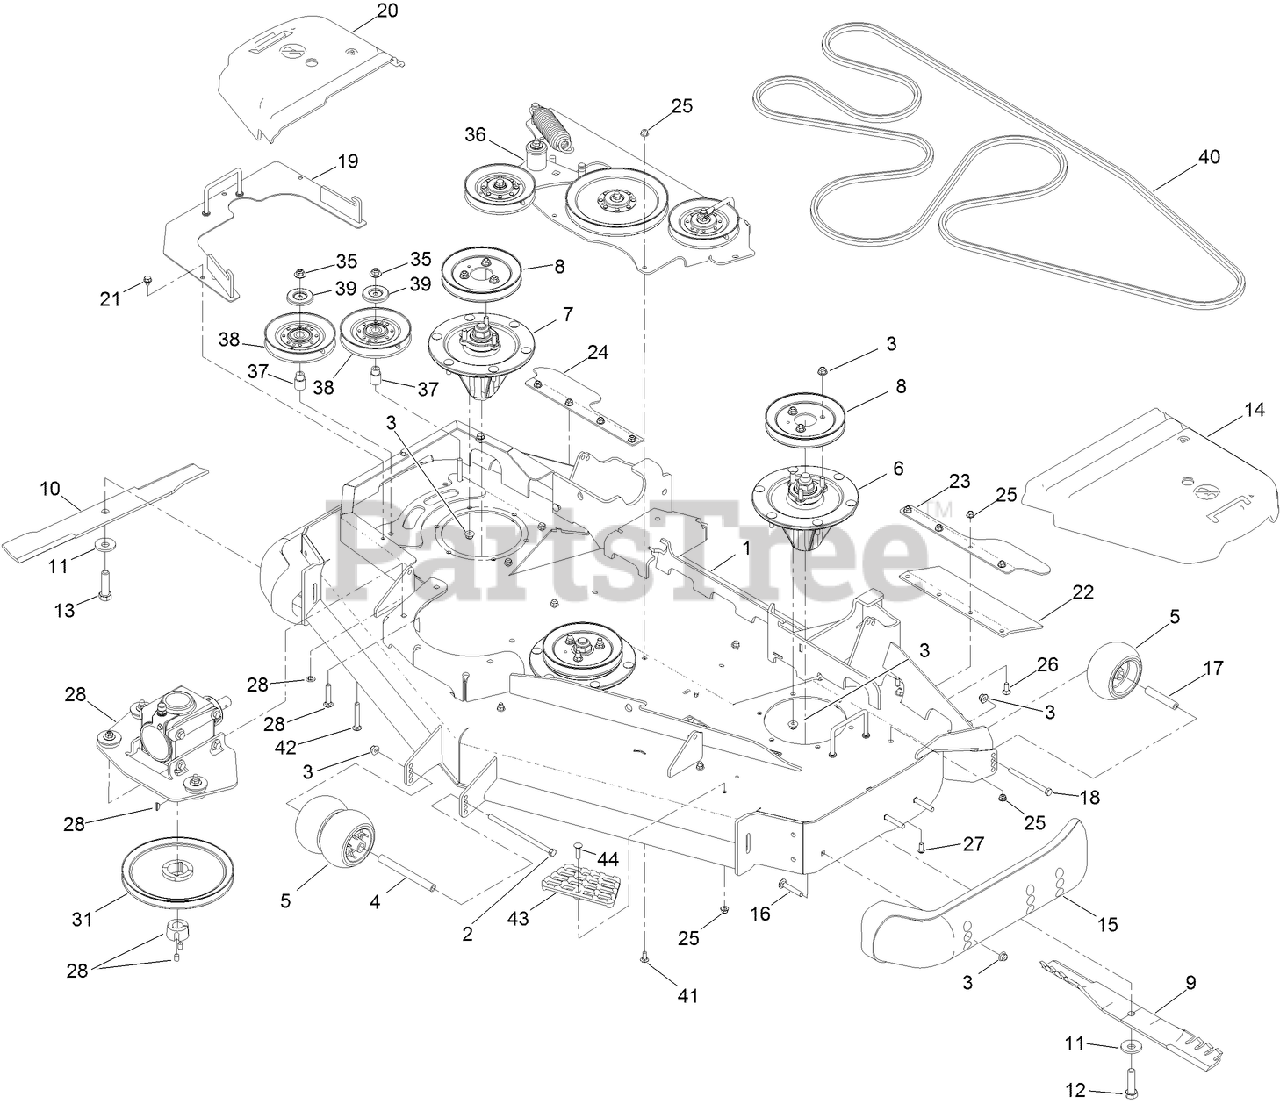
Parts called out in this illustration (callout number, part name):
1	DECK DECAL ASM
2	SCREW-HH
3	NUT-HF, NI
4	SPACER-WHEEL
5	ROLLER-SCALP, ANTI
6	SPINDLE ASM
7	LH SPINDLE ASM
8	PULLEY
9	BLADE-ATOMIC, 20.5IN
10	BLADE-ROTARY, 20.5IN LOW FLOW
11	WASHER-BLADE BOLT, HEAVY
12	SCREW-BLADE
13	SCREW-BLADE, LH
14	COVER-BELT, LH
15	SKID-BUMPER, DECK
16	SCREW-HH
17	TUBE-SPANNER
18	SCREW-HH
19	COVER-DRIVE REVERSE
20	COVER-BELT, RH
21	SCREW
22	GUARD-TIRE
23	SUPPORT-FLAP, OUTER (LH)
24	SUPPORT-FLAP, OUTER (RH)
25	NUT-HF, NI
26	SCREW-CARR
27	SCREW-HSBH
28	GEARBOX ASM
31	PULLEY
35	NUT-FLANGE, NI
36	IDLER MOUNT ASM
37	STANDOFF-IDLER
38	IDLER V
39	SHIELD-DUST
40	BELT-BB
41	SCREW-CARR
42	SCREW-CARR
43	STEP-DECK
44	SCREW-CARR
